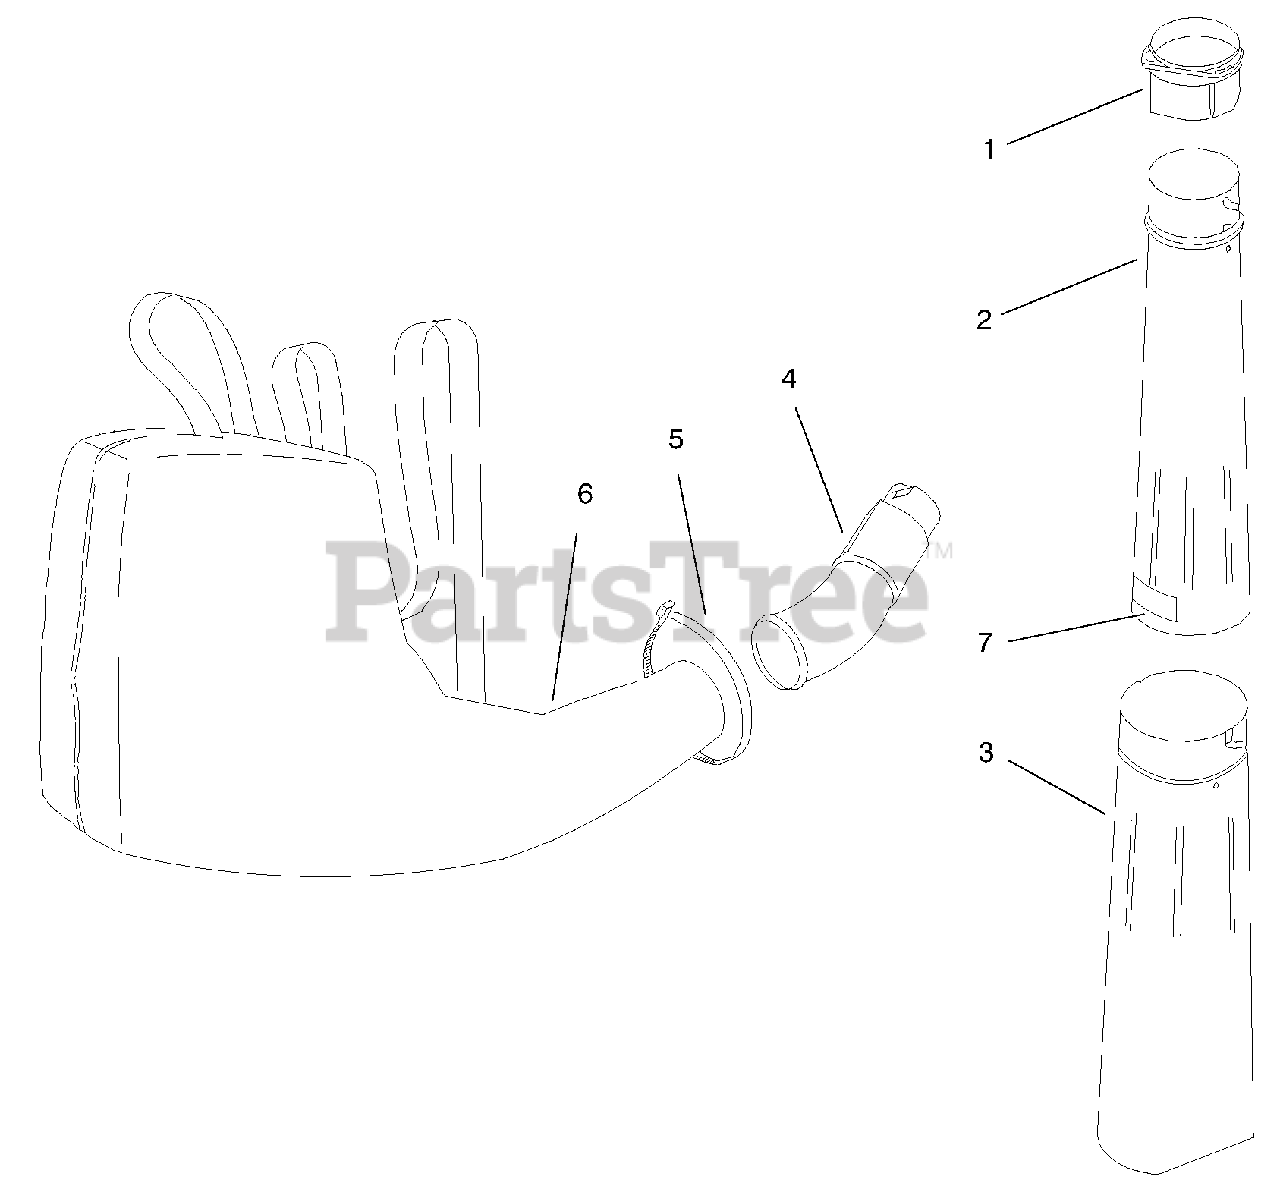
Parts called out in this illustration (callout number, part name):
1	Vacuum Tube Adapter
2	Upper Vacuum Tube and Adapter
3	Lower Vacuum Tube
6	Vacuum Bag Asm. (Incl. Ref. #3 and 4)
7	Decal-Warning
